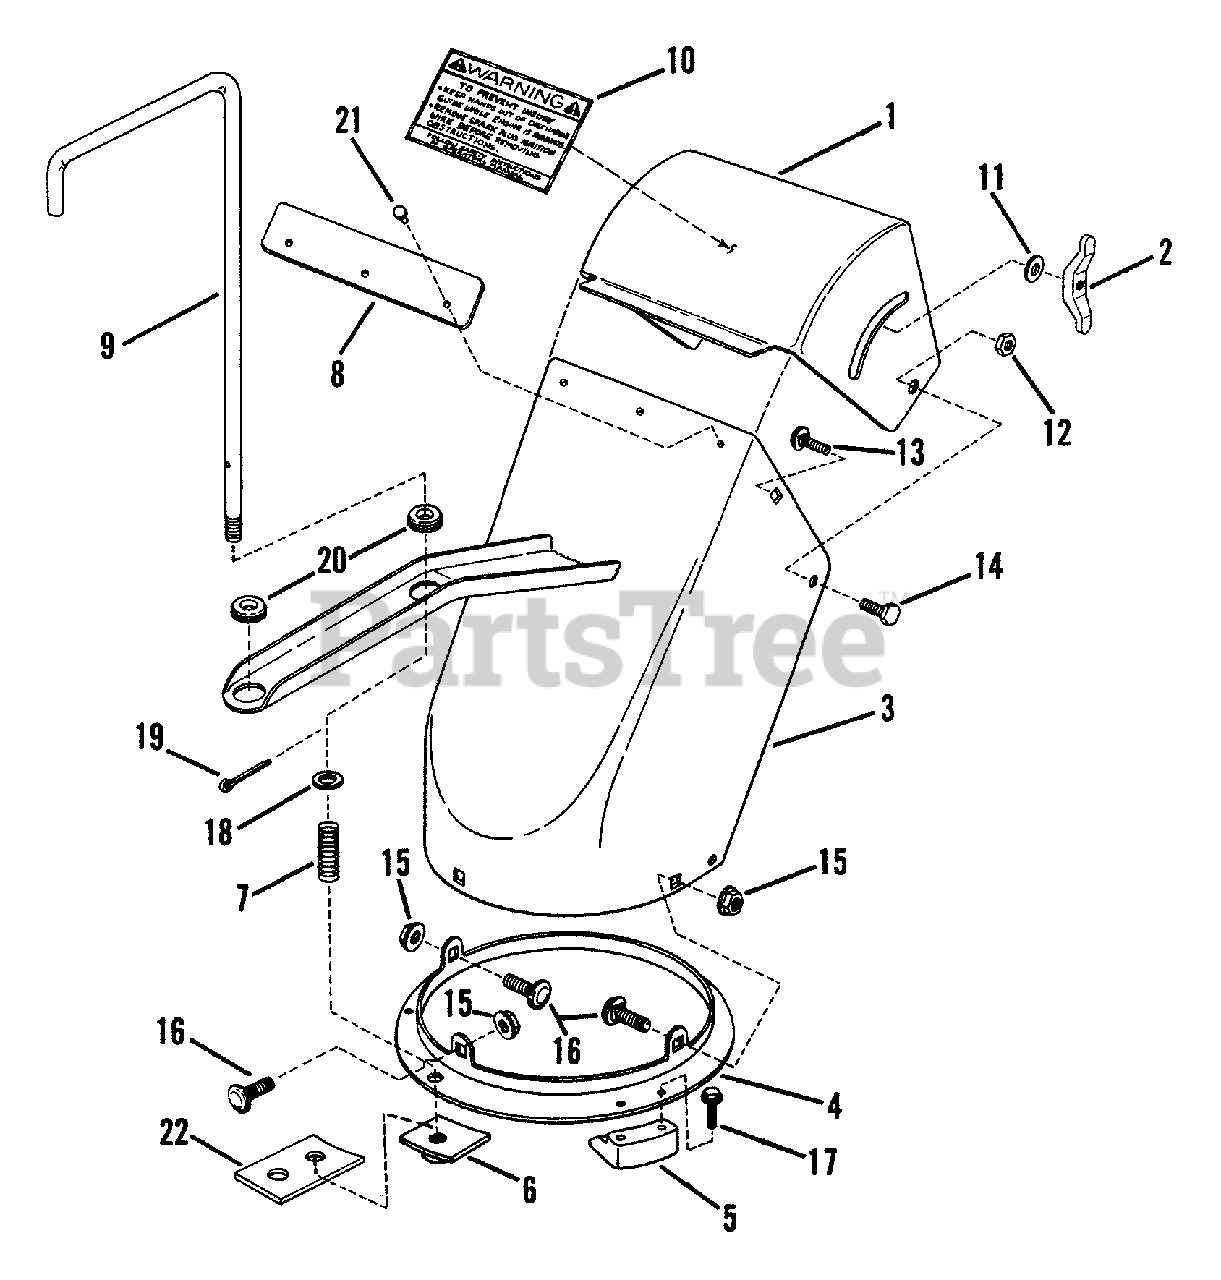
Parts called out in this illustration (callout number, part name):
1	DEFLECTOR, Discharge
2	WING-NUT, 1/4-20
3	CHUTE, Discharge
4	RING, Chute
5	RETAINER (Chute Ring to Housing)
6	BRAKE SHOE
7	SPRING
9	ROD, Release
10	DECAL, Deflector Warning
11	WASHER, 1/4" SAE
12	NUT, 5/16-5/16-18 Hex Center Lock
13	BOLT, 1/4-20 x 3/4" Short Neck Carriage, Grade 5
14	SCREW, 5/16-18 x 1/2" Hex Head Cap, Grade 2
15	NUT, 5/16-18 Hex Flange
16	BOLT, 5/16-18 x 1/2" Short Neck Carriage, Grade 5
17	SCREW, #10-24 x 5/8" Hex Washer Face
18	WASHER, 5/16 SAE Flat
19	COTTER PIN, 1/16 x 3/4"
20	GROMMET, Rubber
22	PAD, Brake
